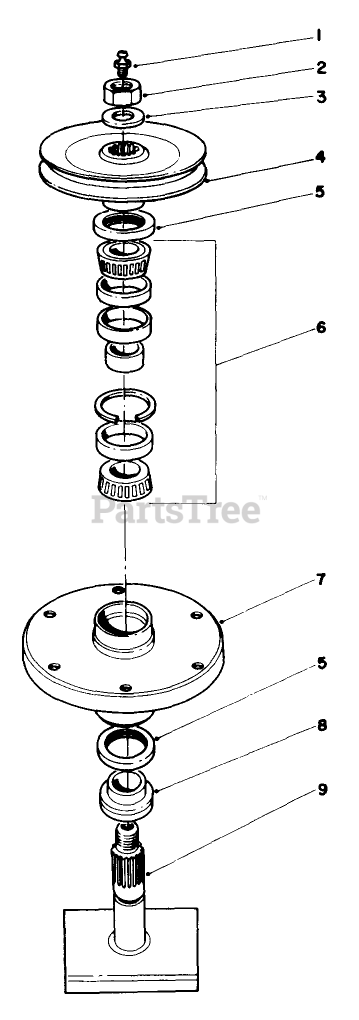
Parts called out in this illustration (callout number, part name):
1	FITTING-GREASE
2	NUT-HEX
3	WASHER
4	PULLEY & HUB WA
5	SEAL-OIL
6	BEARING ASM
7	HOUSING-SPINDLE
8	SPACER
9	SHAFT
